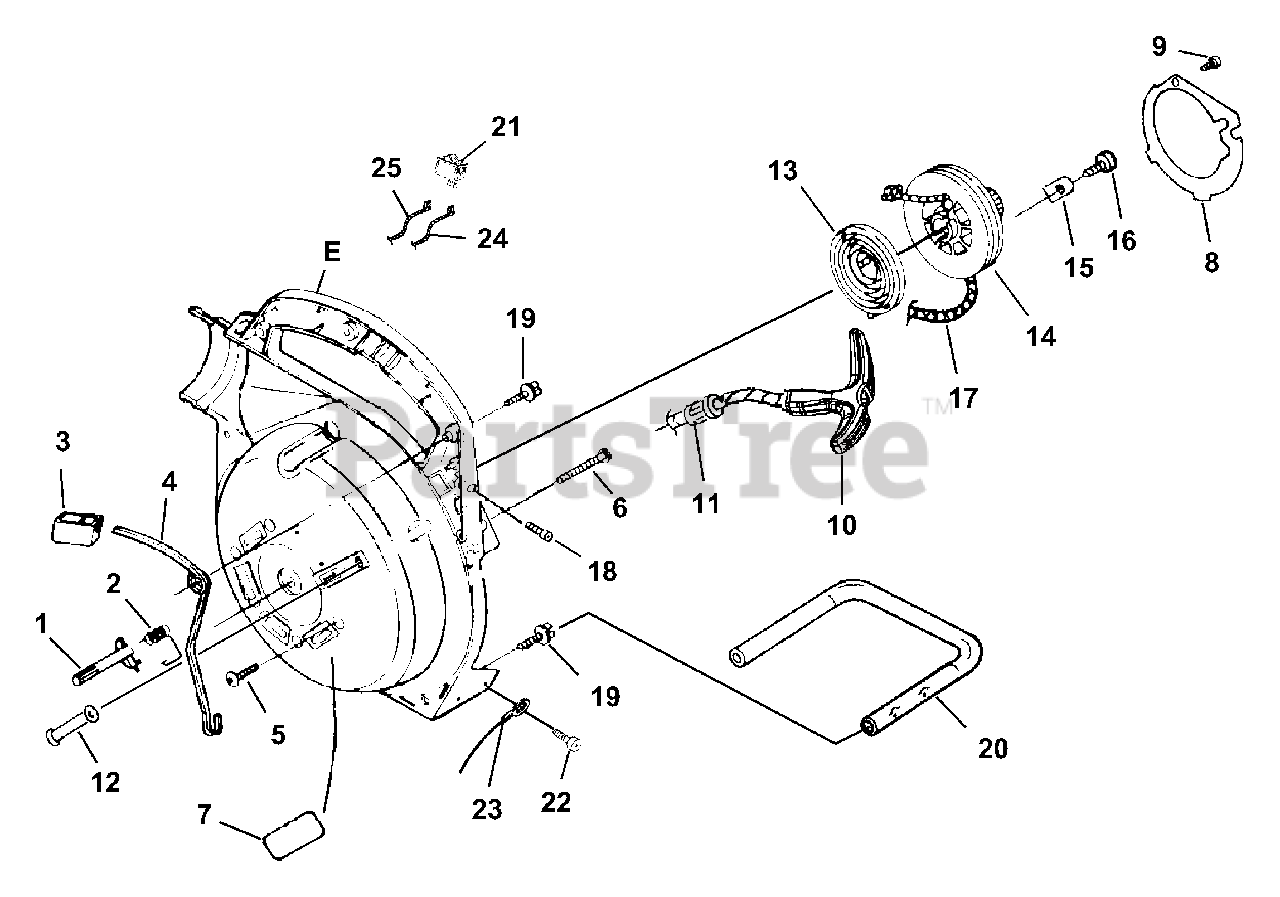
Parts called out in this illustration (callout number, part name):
1	LATCH-Throttle
2	SPRING-Throttle Latch
3	TRIGGER-Throttle
4	LEVER-Throttle
5	SCREW-Thread Form. (10-24 X 3/4")
6	SCREW-Thread Form. (#10 X 1 5/8")
7	KIT-Sealing
8	PLATE-Rotor
9	SCREW-Thread Form. (#6 X 1 3/8")
10	GRIP-Starter (Yellow)
11	BUSHING-Starter
12	GUIDE-Starter Rope
13	SPRING & CONTAINER
14	PULLEY-Starter
15	BRACKET-Retaining
16	SCREW-Thread Form. (#10 X 1/2")
17	ROPE-Starter
18	SCREW-Phil. Hd. (8-32 X 5/8")
19	SCREW-Thread Form. (10-24 X 3/4")
20	HANDLE
21	SWITCH-Momentary
22	SCREW
23	LEAD-Ground
24	Lead-Ground to Switch
25	Lead-Ignition to Switch
E	VOLUTE HOUSING & STARTER
